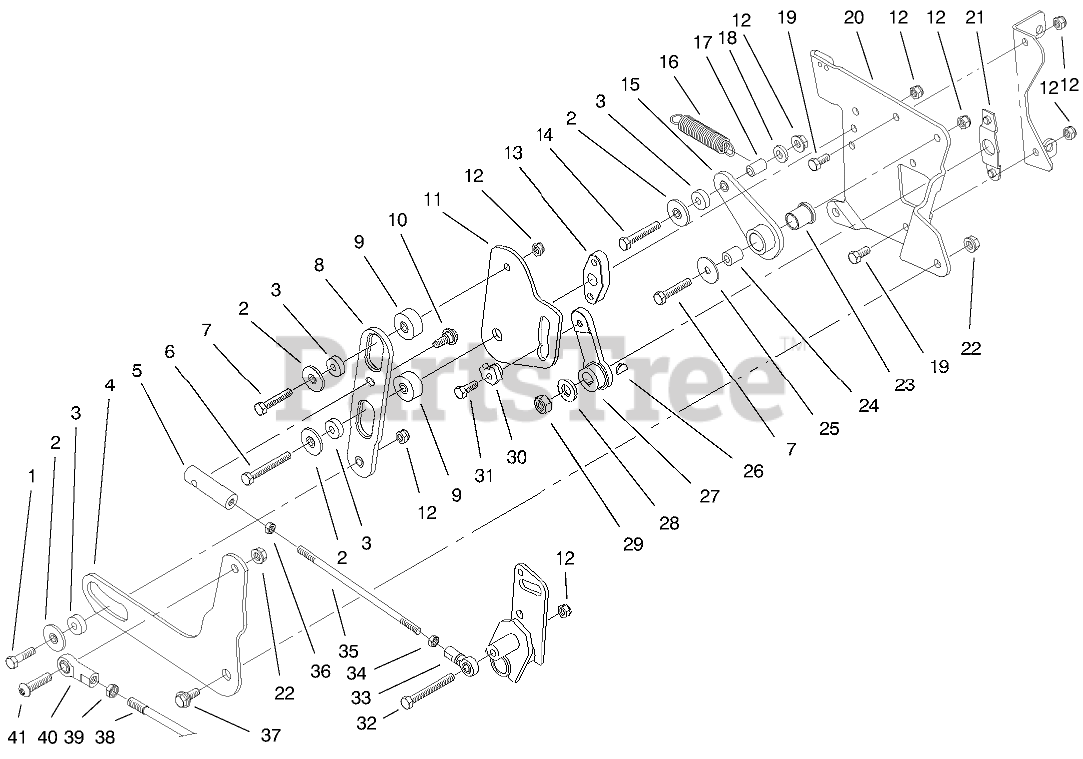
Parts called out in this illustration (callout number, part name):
1	SCREW-HH
2	RETAINER-BEARING
3	BEARING-BALL
4	SLIDER-LIFT
5	END-ROD, RH
6	SCREW-HH
7	SCREW-HH
8	SLIDER-CONTROL, SPEED
9	STANDOFF-CAM PLATE
10	BOLT-SHOULDER
11	PLATE-CAM
12	NUT-LOCK, NI
13	STANDOFF-SLIDER
14	SCREW-HH
15	ARM-RETURN TO NEUTRAL
16	SPRING-IDLER
17	STANDOFF-SPRING
18	WASHER-PLAIN
19	SCREW-HH
20	PLATE-CONTROL
21	LOCATOR-CONTROL PLATE
23	BUSHING-FLANGED
24	SPACER
25	WASHER-FLAT
26	KEY-WOODRUFF
27	ARM-CONTROL, SPEED
28	WASHER-FLAT
29	NUT-LOCK, NI
31	SCREW-THREAD LOCKING
32	SCREW-HH
33	END-ROD, RH
34	NUT-JAM
35	ROD-SLIDER TO PIVOT
36	NUT-JAM
37	BOLT-SHOULDER
38	ROD-LIFT
39	NUT-HJ
40	END-ROD, FEMALE
41	SCREW-HSBH
